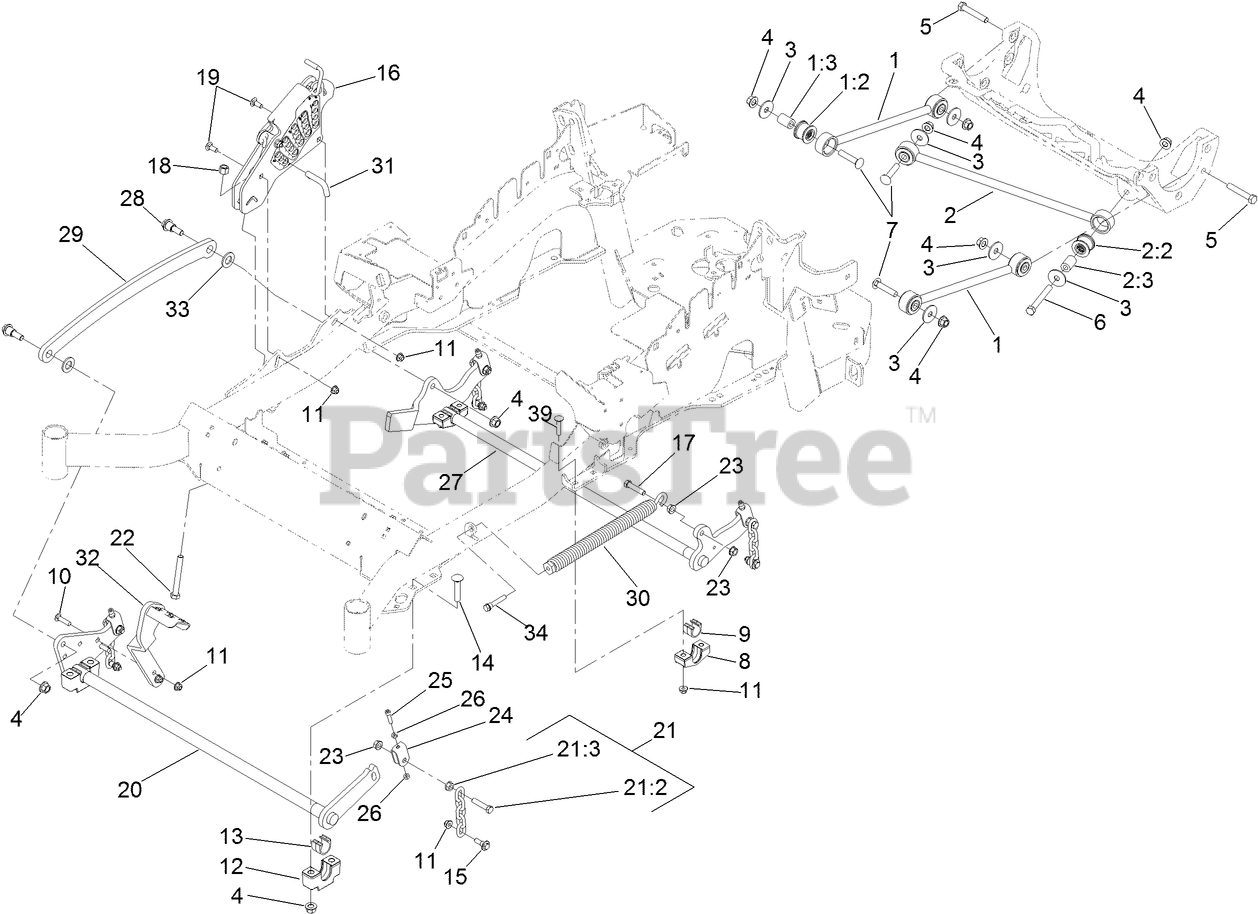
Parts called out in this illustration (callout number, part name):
1	DECK STRUT ASM
1:2	BUSHING-SUSPENSION, RUBBER
1:3	SPACER
2	PANHARD ROD ASM
2:2	BUSHING-SUSPENSION, RUBBER
2:3	SPACER
3	WASHER-THRUST
4	NUT-LOCK
5	SCREW-HH
6	SCREW-HH
7	SCREW-CARR
8	SUPPORT-CROSS SHAFT, REAR BEARING
9	BEARING-CROSS SHAFT, REAR
10	SCREW-CARR
11	NUT-HF, NI
12	SUPPORT-CROSS SHAFT, BEARING
13	BEARING-CROSS SHAFT, FRONT
14	BOLT-CARR
15	SCREW-SHOULDER, HHF
16	HOC ASM
17	SCREW-HH
18	NUT-LOCK, NI
19	BOLT-CARR
20	CROSS SHAFT-FRONT
21	DECK LIFT CHAIN ASM
21:2	SCREW-HH
21:3	NUT-HF
22	BOLT-TAP
23	NUT-HF
24	YOKE-ADJUST, DECK
25	SCREW-HSH
26	NUT-JAM
27	LIFT-DECK, REAR
28	SCREW-SHOULDER, HHF
29	LINK-LIFT, DECK
30	SPRING-EXTENSION
31	PIN-HOC
32	LEVER-FOOT
33	WASHER-FLAT
34	BOLT-SHOULDER
39	SCREW-CARR
